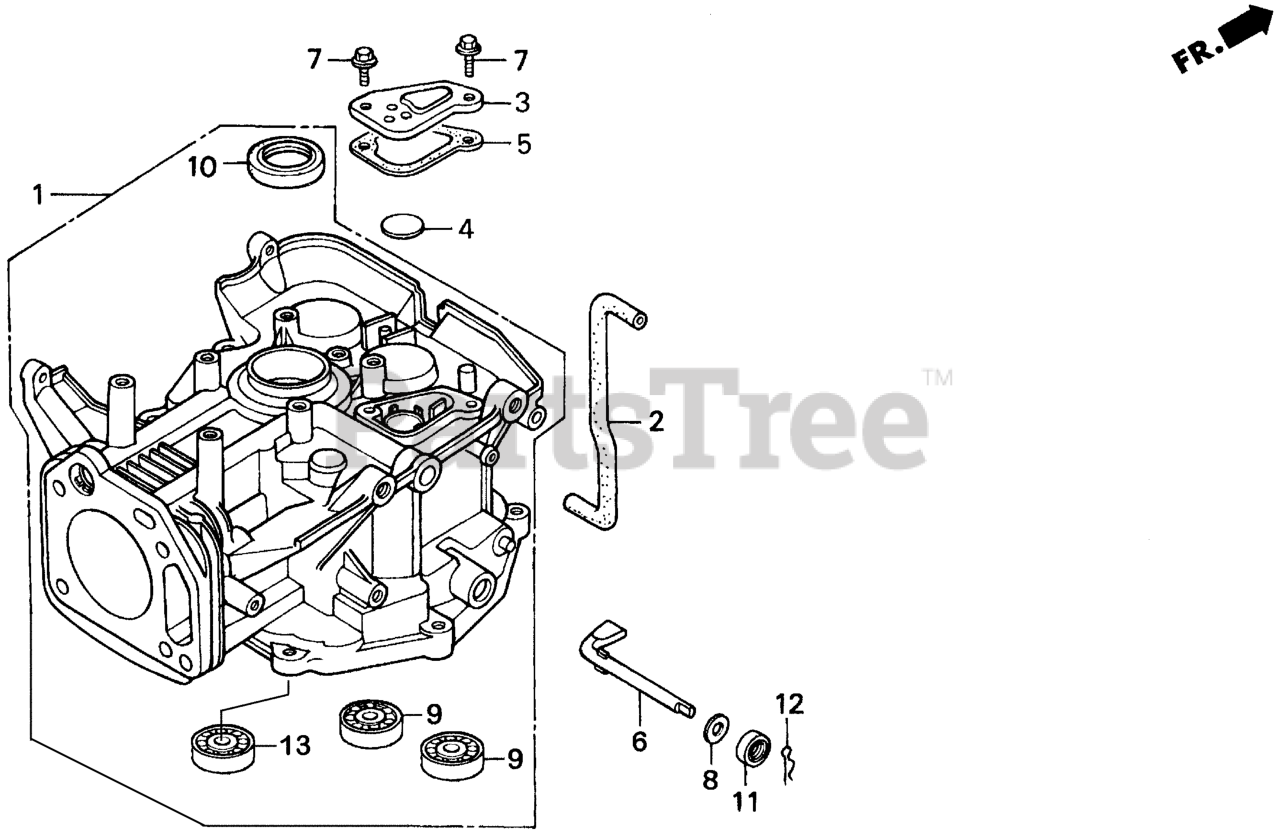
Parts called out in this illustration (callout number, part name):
1	CYLINDER ASSY.
2	TUBE, BREATHER
3	CAP, BREATHER CHAMBER
4	VALVE, BREATHER
5	GASKET, BREATHER CAP
6	SHAFT, GOVERNOR ARM
7	BOLT, FLANGE (6X12) (CT200)
8	WASHER, THRUST (8.1MM)
9	BEARING, RADIAL BALL (6202)
10	OIL SEAL (35X52X8)
11	OIL SEAL (8X14X5)
12	PIN, LOCK (10MM)
13	BEARING, RADIAL BALL (6207)
